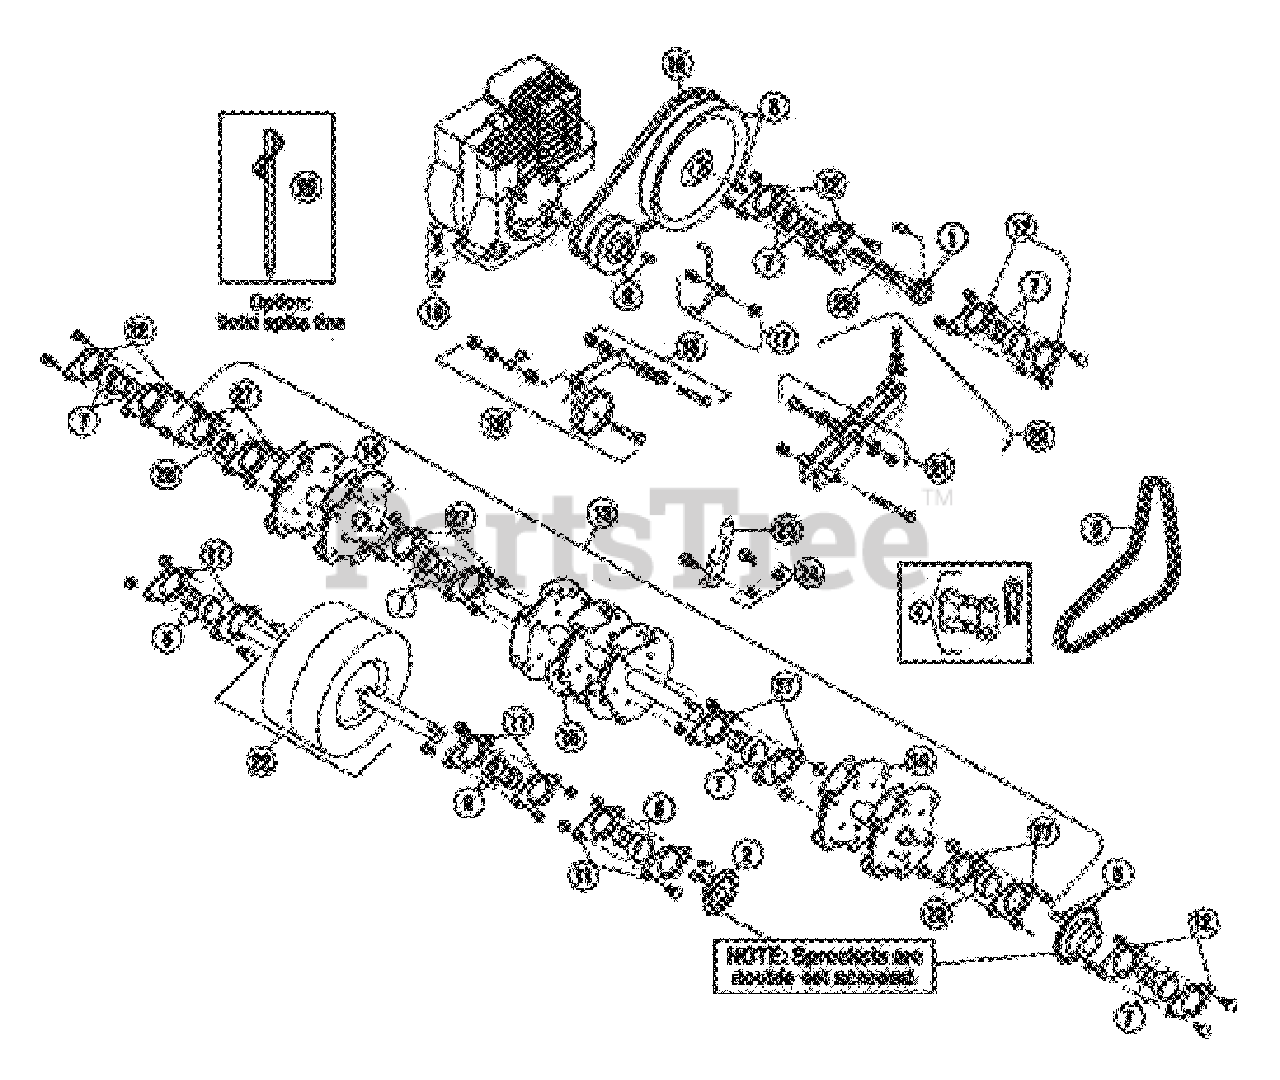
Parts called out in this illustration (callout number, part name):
1	Sprocket, jackshaft, with key
2	Sprocket, wheel, with set screws and key
3	Sprocket, rotor, with set screws and key
4	Master link
5	Chain, #50 perma lube roller
6	Bearing, 3/4" with lock collar
7	Bearing, 1" with lock collar
8	V-pulley, A-4" with set screws and key
9	V-pulley, A-10" with set screws and key
10	V-belt, A-44" special
11	Stamping kit w/fasteners
12	Stamping kit w/fasteners
13	Tine rotor shaft assembly, complete
14	Outer rotor plate kit
15	Center tine rotor shaft
16	Fastener kit, engine
17	Belt keeper kit
18	Idler arm kit, pulley
19	Idler pulley kit
20	Idler arm kit, chain
21	Idler sprocket kit, chain
22	Front wheel and shaft kit
23	Tine set, closed spoon, 42 each
23	Tine set, closed spoon, 6 each
24	Tine/spike fastener kit, 96 ea. bolts and nuts
24	Tine/spike fastener kit, 12 ea. bolts and nuts
25	Jackshaft, with key
26	Spike set, 42 each
27	Stamping kit
28	Bearing 1"
